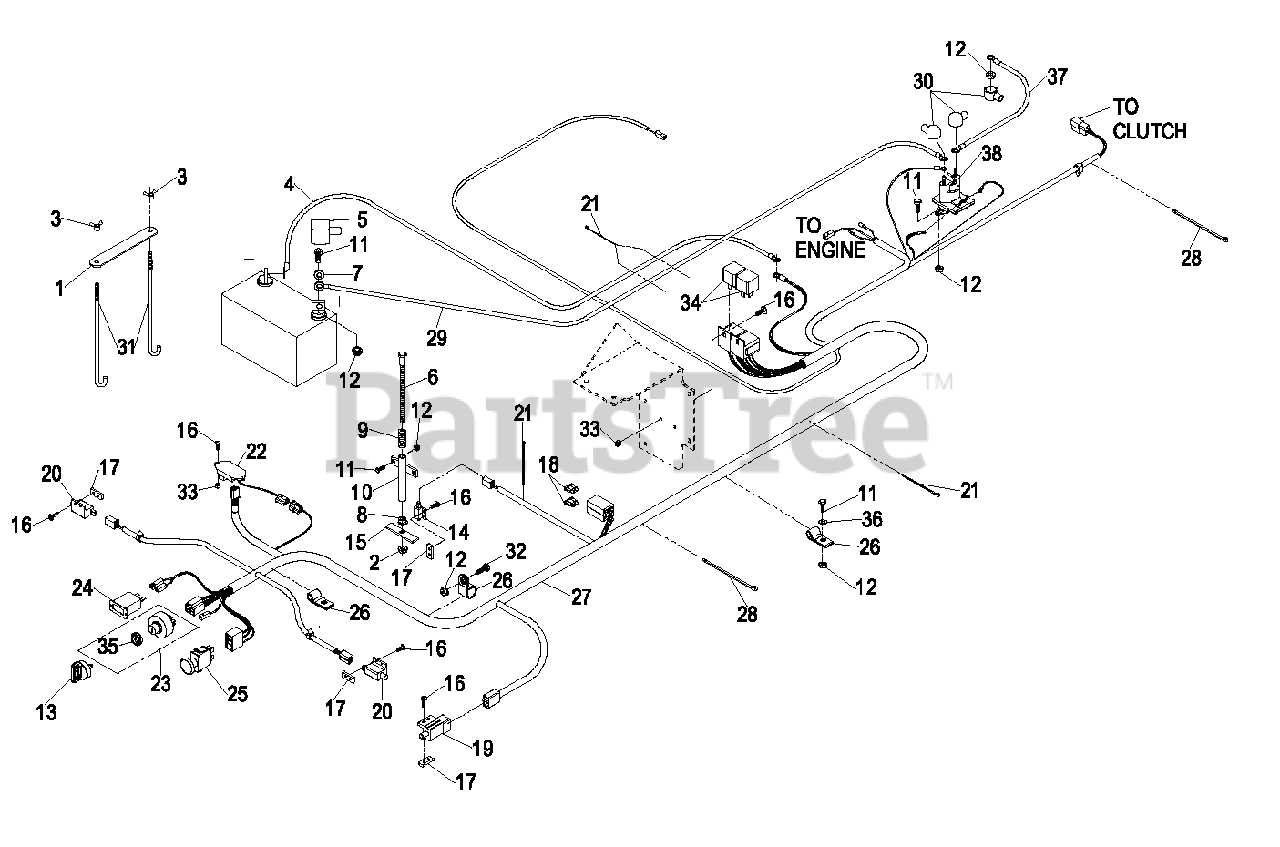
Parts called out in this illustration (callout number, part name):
1	STRAP-HOLDDOWN, BATTERY
2	NUT-LOCK, NI
3	WINGNUT
4	WIRE-GROUND
6	SCREW-HH
7	WASHER-FLAT
8	NUT-HEX
9	SPRING-SWITCH, SEAT
10	MOUNT-SPRING, SEAT
11	SCREW-HH
13	KEY-IGNITION
13	KEYS-IGNITION (SPARE PAIR
14	SWITCH-CLOSED, NORMALLY
15	PLATE-SWITCH, SEAT
16	SCREW-PPH
17	PLATE-TAPPED
18	FUSE-BLADE TYPE, 20 AMP
20	SWITCH-OPEN, NORMALLY
21	TIE-CABLE
22	MODULE-DELAY, SEAT
23	ASM,SWITCH W/NUT
24	METER-HOUR
25	SWITCH-PTO
26	CLIP-LOOM
27	HARNESS,WIRE LAS KA
28	TIE-PLASTIC
30	INSULATOR-SOLENOID
31	BOLT-HOLDDOWN
32	SCREW-HH
33	NUT-LOCK, NI
35	NUT-SWITCH, IGNITION
36	WASHER-FLAT
